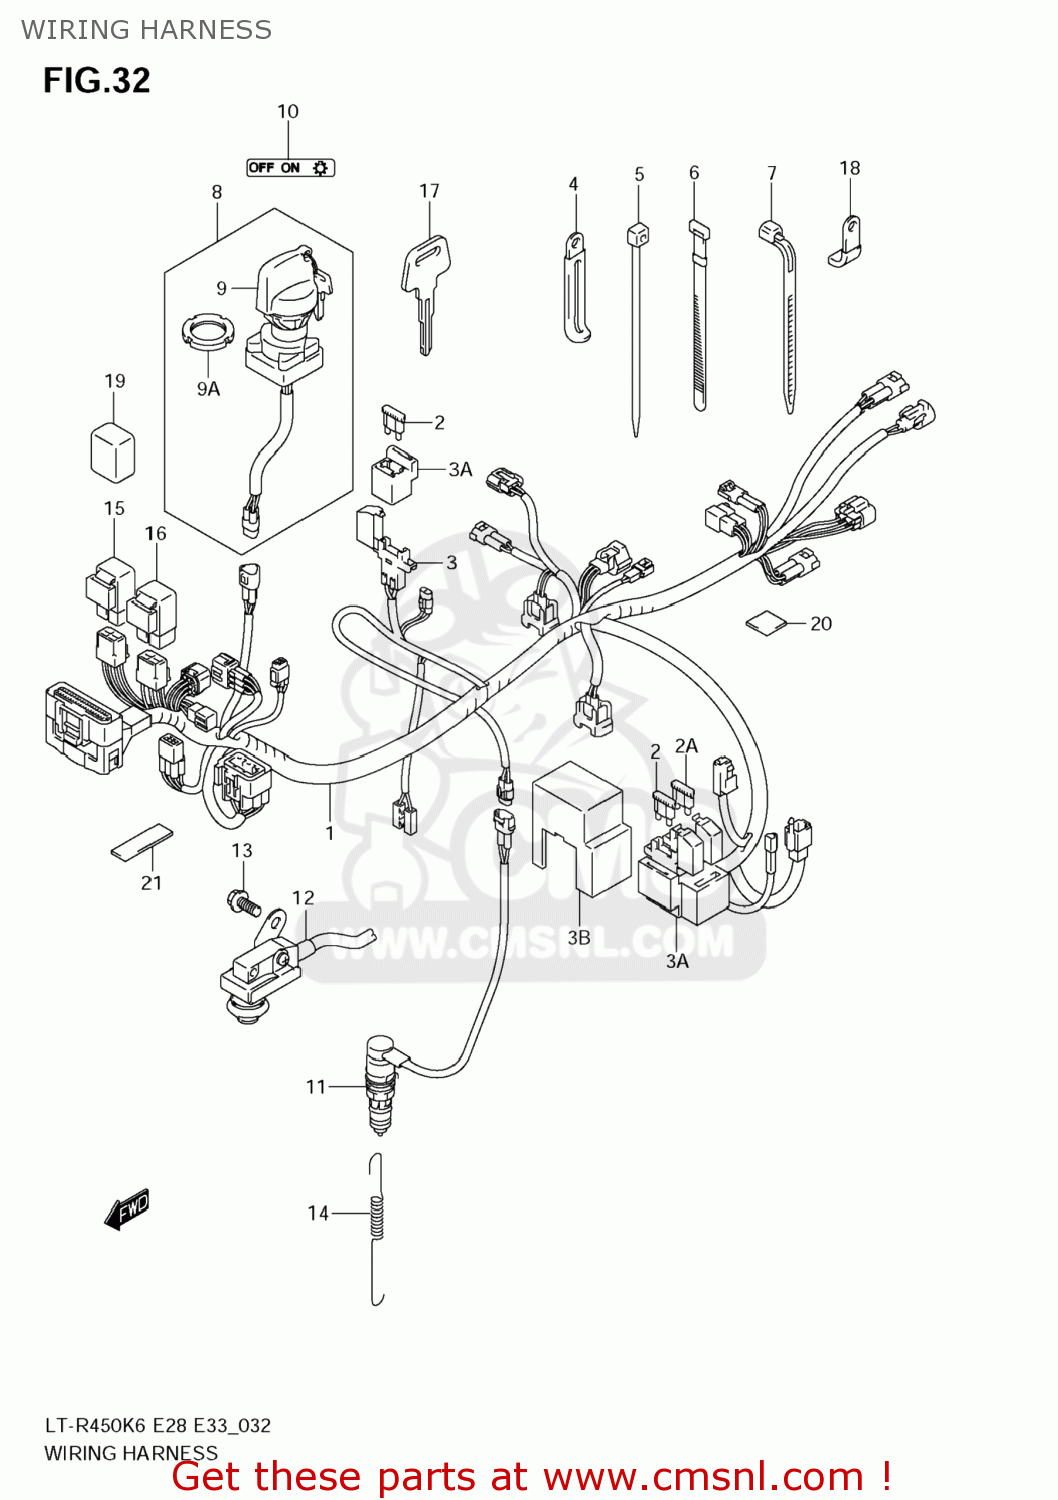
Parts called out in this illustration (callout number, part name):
1	HARNESS,WIRING
2	FUSE(10A)
2A	FUSE(20A)
3	HOLDER,FUSE
3A	HOLDER
3B	COVER,FUSE
4	CLAMP(L:45)
5	CLAMP(L:154)
6	CLAMP(L:120)
7	CLAMP(L:125)
8	SWITCH ASSY,IGNITION
9	MASCOT,KEY
9A	NUT,IGNITION SWITCH
10	PLATE,CONTROL IDENTIFICATION
11	SWITCH ASSY,STOP LAMP
12	SWITCH ASSY,STOP LAMP
13	SCREW
14	SPRING
15	RELAY ASSY
16	RELAY ASSY
17	KEY,BLANK(TYPE:C)
18	CLAMP
19	COVER,CONNECTOR
20	PROTECTOR(30X80X1)
21	PROTECTOR,WIRING HARNESS
